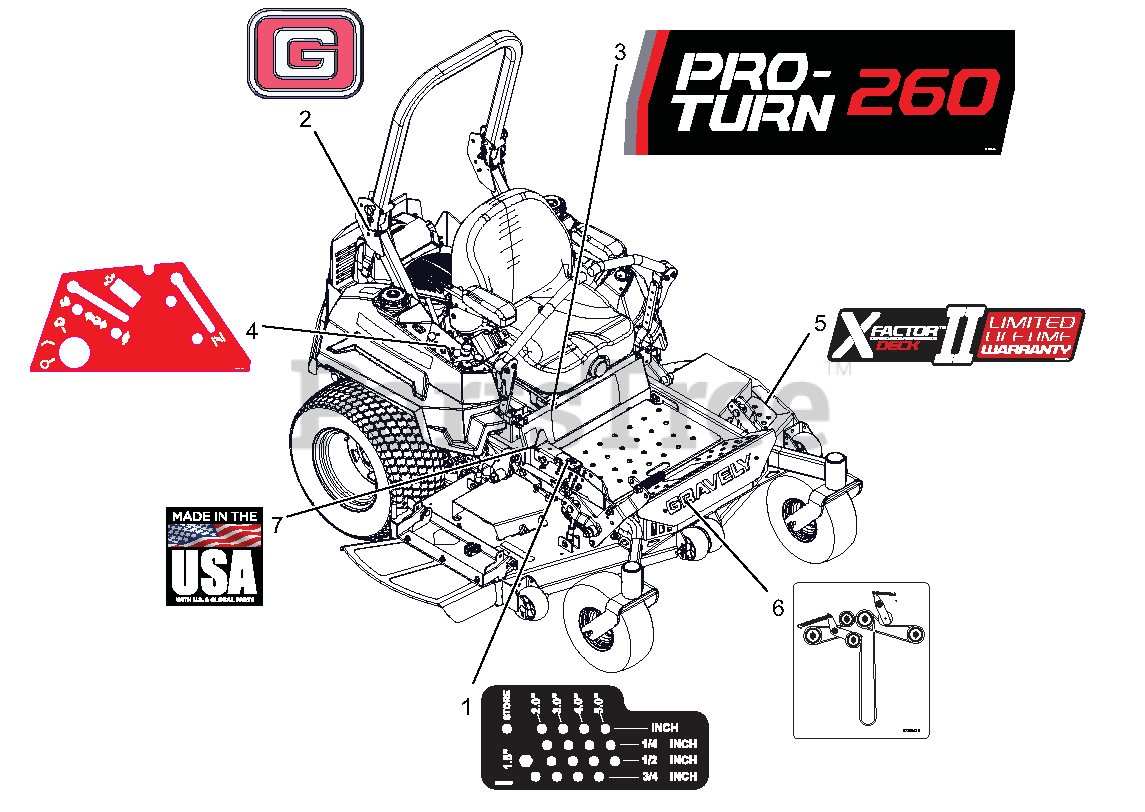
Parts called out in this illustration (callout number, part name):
1	DECAL, HEIGHT OF CUT
2	DECAL, GRAVELY BRAND
3	DECAL, PRO-TURN 260
4	DECAL, NON-EFI CONTROL PANEL
5	DECAL, X-FACTOR DECK
6	DCL,BELT ROUTE-RH BK-SIDE IDLR
7	DECAL, MADE IN USA
